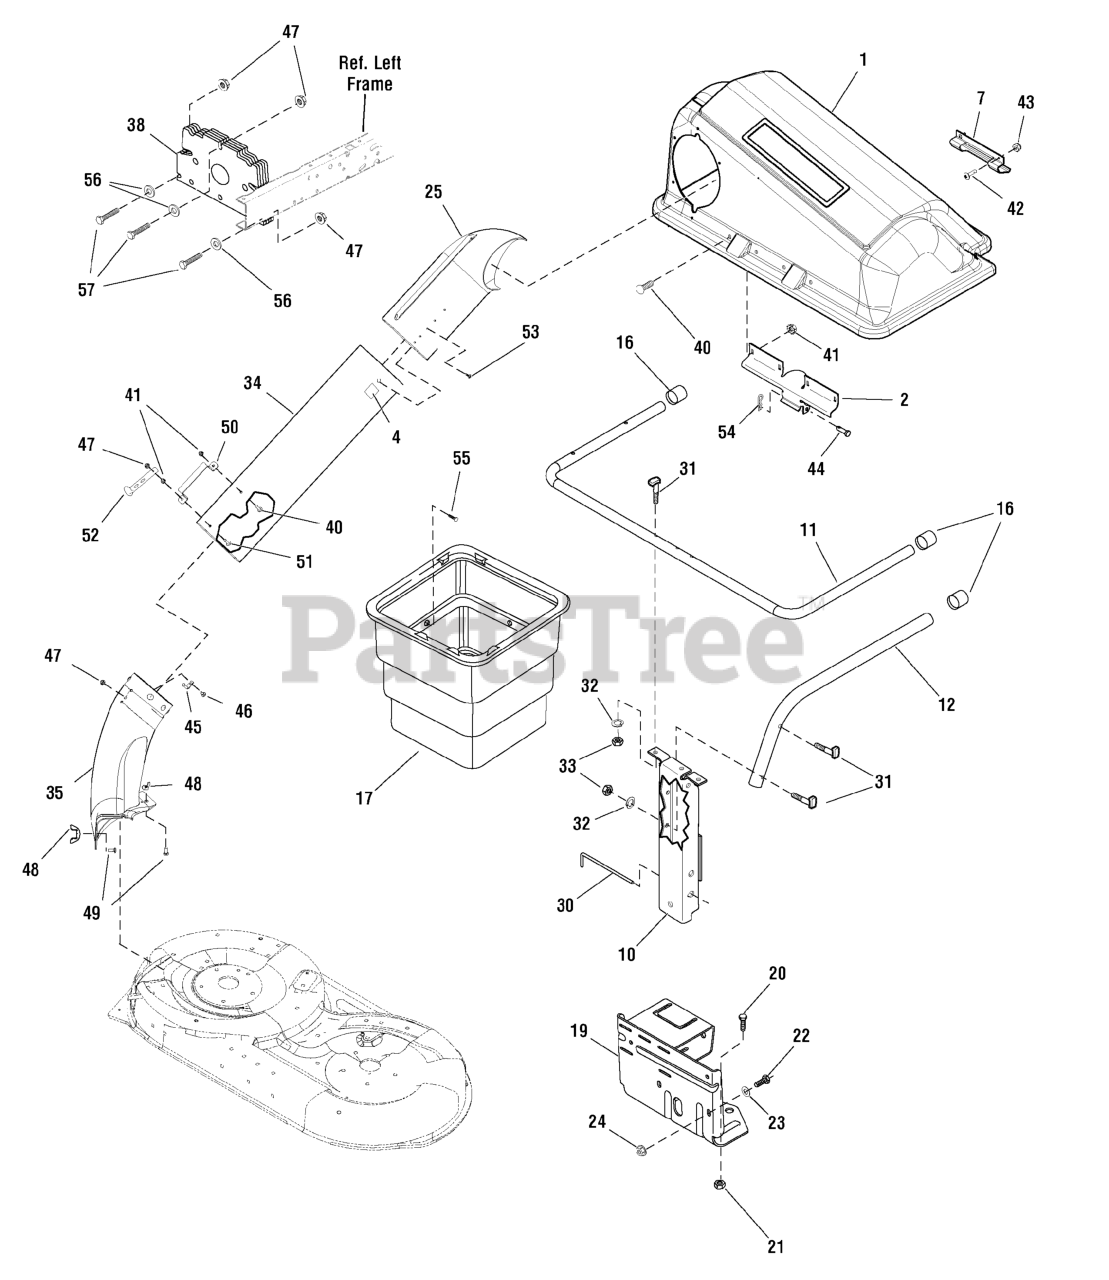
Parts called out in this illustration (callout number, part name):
1	COVER, 38" / 40
2	HINGE COVER
4	DECAL, Instruction / Caution, Grass Catcher
7	HANDLE, Plastic
10	CHANNEL & PLATE ASSEMBLY
12	TUBE, Center
16	PLUG, End
17	ASSEMBLY, Nestable Container
19	BAGGER MOUNT
20	BOLT, Hex, 1/2-13 x 1-1/4
21	NUT, Lock, 1/2-13
22	BOLT, Hex, 5/16-18 x 1
24	NUT, Flange, 5/16-18
25	ELBOW, Upper Tube
30	PIN, Channel Mount
31	BOLT, Special, 5/16-24
32	WASHER, Splitlock, 5/16
33	NUT, 5/16-24
34	TUBE, Connecting
35	EXTENSION, Tube
38	WEIGHT, Front
40	SCREW, Machine, 1/4-20
41	NUT, Lock, KEPS, 1/4-20
42	SCREW, Machine, 10-24 X 5/8
43	NUT, Lock, 10-24
44	PIN, Cover Hinge
45	PIN, Latch
46	BOLT, Carriage, 1/4-20 x 5/8
47	NUT, Flangelock, 1/4-20
48	WINGNUT, 5/16-18
49	BOLT, Carriage, 5/16-18 x 3/4
50	HANDLE, Connect Tube
51	SCREW, Machine, 1/4-20 x 1
52	LATCH, Rubber
53	SCREW, 1/4
54	PIN, Hair
55	FASTENER, Panel
56	WASHER, Flat, 1/4
57	BOLT, Hex, 1/4-20 x 2
60	BLADE, 38, Export
61	BLADE, Hi Lift, 40
62	BLADE, Low Lift, 42
